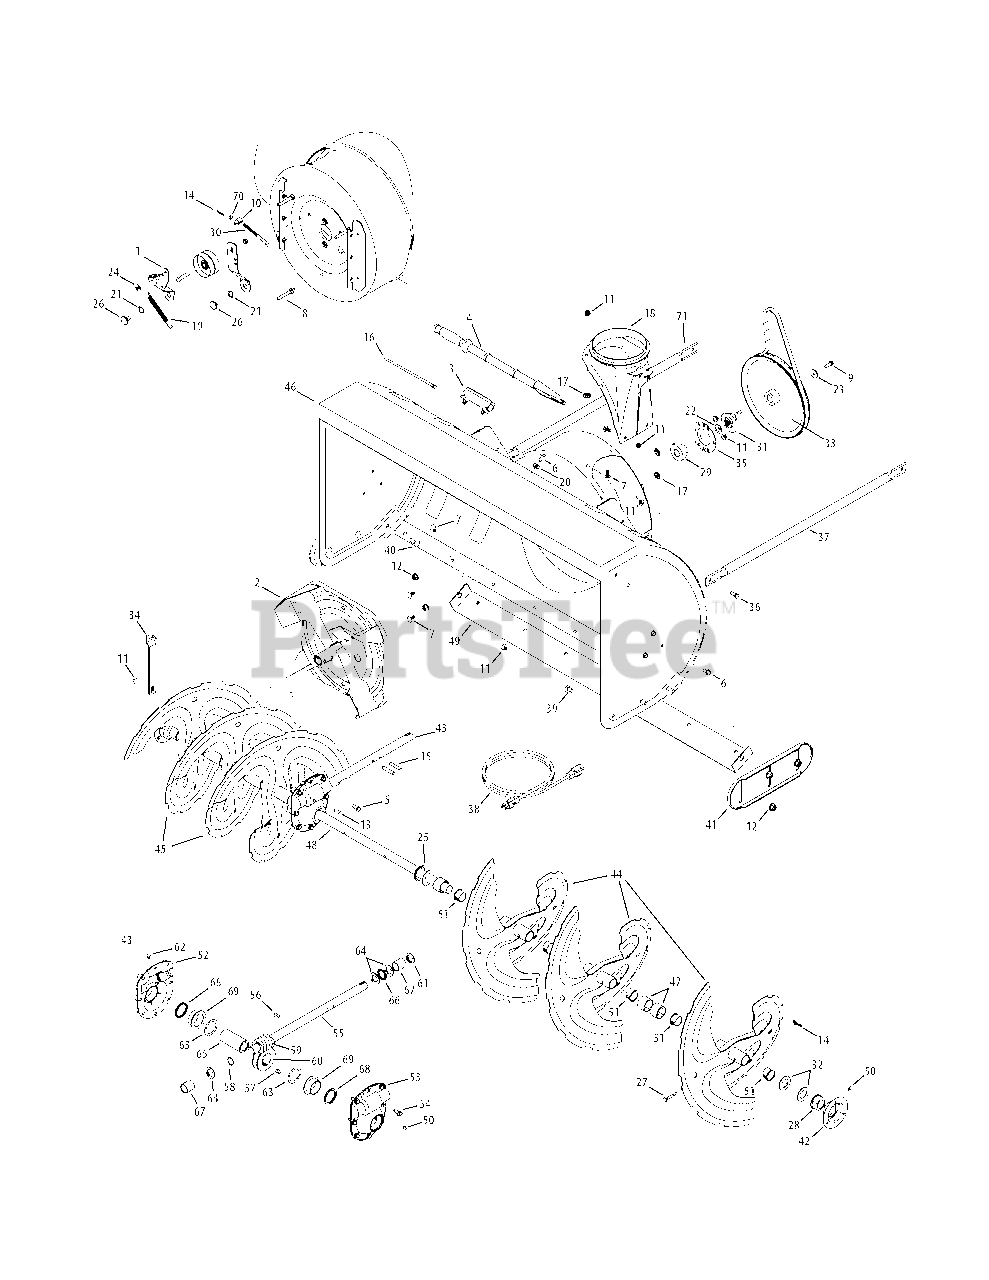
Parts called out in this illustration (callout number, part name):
1	Bracket Assembly, Auger Brake
2	Impeller , 16"
3	Clip, Mounting
4	Tool, Clean-out
5	Screw, Hex Cap, 5/16-18 x 1.0 Gr5
6	Screw, 5/16-18 x .750
7	Screw, Carriage, 5/16-18 x .75
8	Screw w/Stud, 5/16-18 x .4300
9	Screw, Hex Cap Lock, 5/16-24, 875
11	Nut, Hex Flange Lock, 5/16-18
12	Nut, Hex Flange Lock, 3/8-16
13	Key, Woodruff, 1/4 x 3/4
14	Pin, Bow-tie Cotter
15	Pin, Spiral, 5/16 x 1.75
16	Cable Tie
17	Nut, Push
18	Adapter, Chute, 6"
19	Spring, Extension
20	Washer, Flat, .349 x .879 .063
21	Washer, Wave, .625 x .885 x .015
22	Washer, Bell., .78 x 1.49 x .06
23	Washer, Flat, .34 x 1.5 x .15 Ht.
24	Washer, .344 x .75 x .12
25	Washer, 1.01 x 1.86 x .06
26	Screw, Shoulder, .625 x .17
27	Pin, Shear, .25 x 1.75
28	Bearing, Flange w/Flats
29	Bearing, Self Aligning
30	Rod, Auger Idler
31	Adapter, Pulley w/Pins
32	Spacer, 1.004 x 1.375 x .25
33	Pulley, Auger Drive, 10.0
34	Bracket, Gear Box Support
35	Housing, Bearing
36	Screw, 5/16-18 x .75 GR5
37	Tube, Support , LH
38	Extension Cord, 110V
39	Screw, Carriage, 3/8-16 x .75
40	Screw, Carriage, 3/8-16 x 1.00
43	Gear Box Assembly
44	Spiral Assembly, LH
45	Spiral Assembly, RH
46	Housing, Auger - 45"
47	Spacer, 1.50 x 1.00 x 1.00
48	Axle, Spiral
49	Shave Plate, 45"
50	Grease Fitting, 3/16
51	Flange Bushing
52	Housing Assembly, Auger, RH
53	Housing Assembly, Auger, LH
54	Screw, LD, 5/16-18 x .750
55	Auger Drive Shaft
56	Key, Hi Pro, 3/16 x 3/4
57	Key, 1/4 x 3/4 Dia.
58	External Retainer Ring
59	Gear, Worm
60	Gear, Worm, LH
61	Seal, Oil
63	Wash, Flat, 1.52ID x 2.0 OD
64	Wash, Flat, .88 ID x .38 OD
65	Worm Gear Shaft
66	Bearing, Thrust
69	Flange Bearing
70	Jam Nut, 5/16-18
71	Tube, Support, RH
